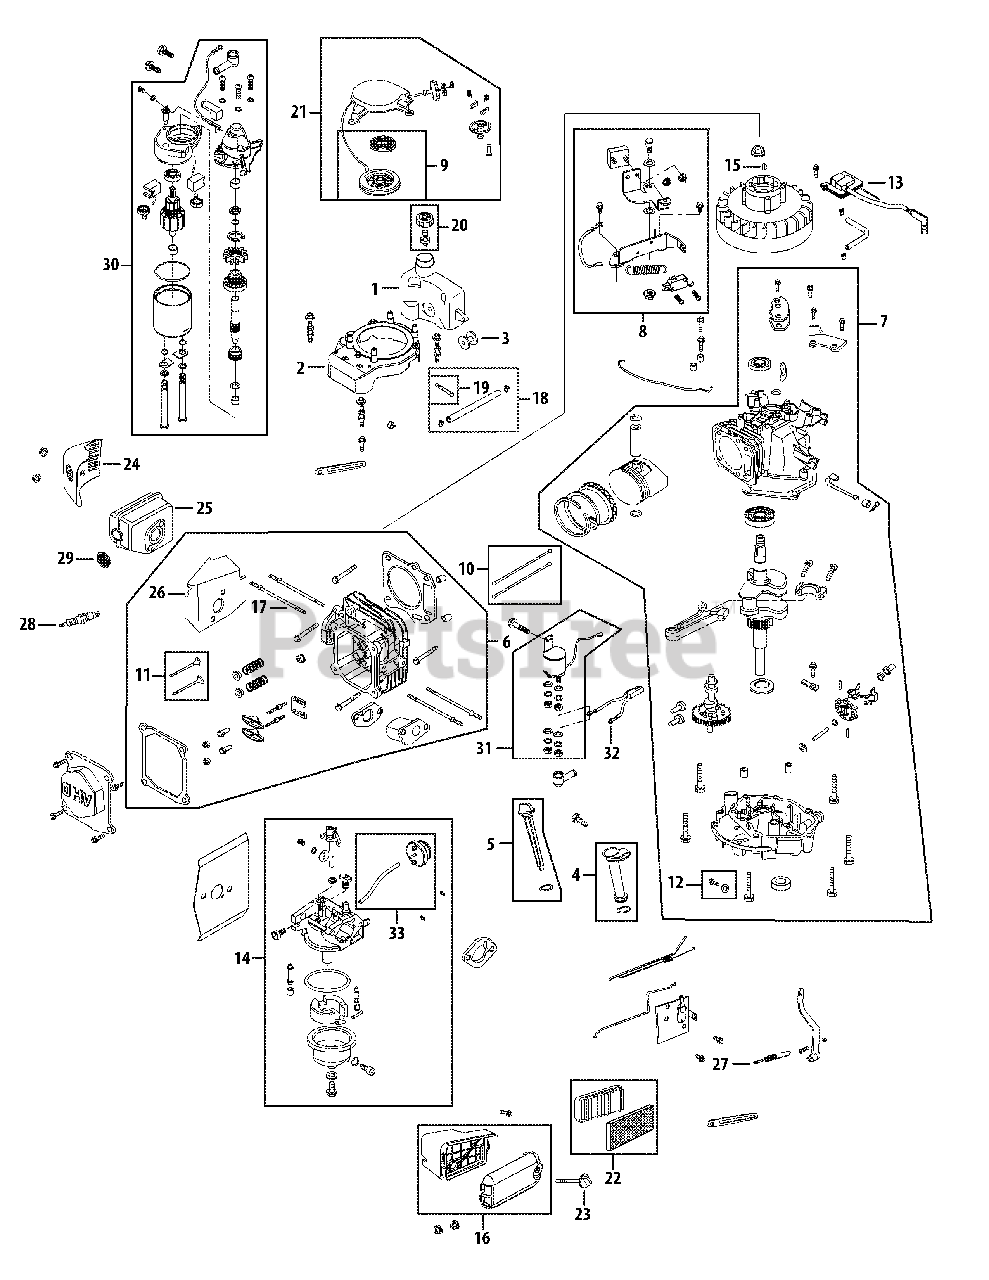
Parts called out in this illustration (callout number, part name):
1	Fuel Tank
2	Flywheel Shroud
3	Rubber Fuel Tank Washer
4	Oil Filler Tube
5	Dipstick Assembly
6	Cylinder Head Assembly
7	Short Block Assembly
8	Stop Switch Brake Assembly
9	Recoil Spring & Pulley Assembly
10	Push Rod Kit
13	Ignition Coil
14	Carburtor Assembly
15	Flywheel Key
16	Air Cleaner Housing Complete
17	Muffler Stud Assembly
18	Fuel Line Kit
19	Fuel Filter
20	Fuel Cap Assembly
21	Recoil Starter Assembly
22	Air Cleaner Kit
23	Air Cleaner Thumb Screw
24	Muffler Guard
26	Muffler Gasket & Heat Shield
27	Governor Return Spring
28	Spark Plug
29	Spark Arresstor
30	Electric Starter
31	Relay Assembly
32	Relay Harness Connector
33	Primer Assembly
